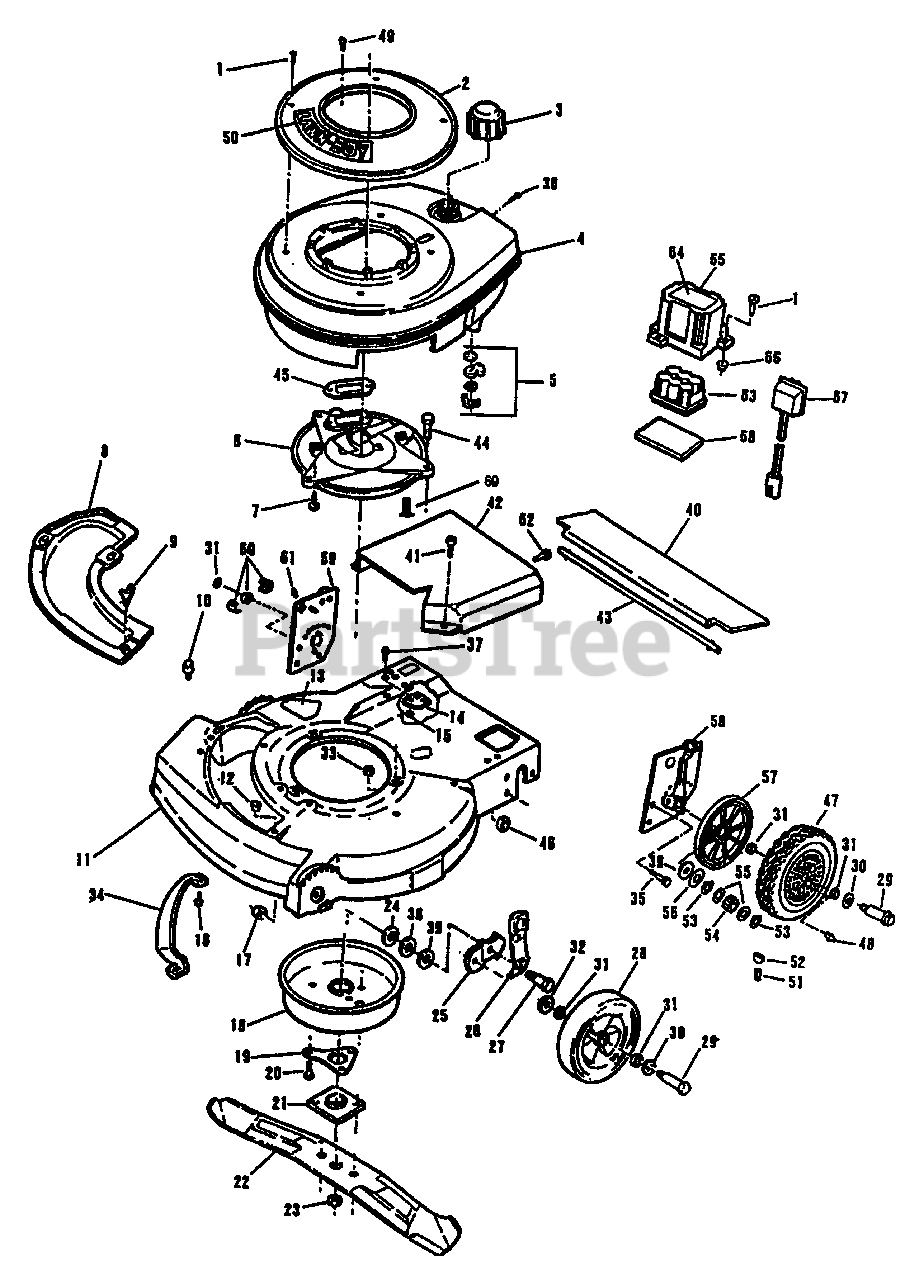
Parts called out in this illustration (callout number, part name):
1	Screw
2	Starter Base and Nut Assembly
3	Fuel Cap
4	Shroud-Engine
5	Fuel Shut-Off Assembly
6	Plate Muffler
7	Screw-Muffler Plate to Block
8	Cover Plate
9	Wing Screw
10	Screw-Plate and Chute Mounting
11	Housing Assembly
12	Grommet
13	Decal-Blade Contact Warning
14	Bolster-Housing
15	Nut-Bolster to Housing
16	Screw
17	Nut
18	Muffler Cover Assembly
19	Support-Crankshaft
20	Screw-Muffler to Muffler Plate
21	Collar and Plate Assembly
22	Blade-21"
23	Nut-Blade
24	Washer
25	Bracket-Wheel Height Adjust
26	Knob and Spring Assembly
27	Bolt-Shoulder
28	Wheel-Front
29	Bolt-Wheel
30	Washer-Felt
31	Washer-Felt
32	Washer
33	Nut-Muffler Plate to Housing
34	Toe Bar
35	Screw-Handle Bracket
36	Screw-Shroud to C.D. Bracket
37	Screw-Bolster to Housing
38	Washer-Shim-Wheel Height Adjust Bracket
39	Washer-Shim-Wheel Height Adjust Bracket
40	Shield-Trailing
41	Screw-Drive Cover Mounting
42	Cover-Drive
43	Rod-Trailing Shield
44	Screw-Muffler Plate to Housing
45	Gasket-Exhaust
46	Locknut-Hdl. Brkt. to Housing
47	Rear Wheel
48	Lube Fitting
49	Screw-Starter Mounting
50	Applique-Starter Base
51	Spring
52	Key
53	Retaining Ring
54	Pinion
55	Spacer
56	Washer
57	Cover-Rear Wheel
58	Height Adjuster Assembly-L.H.
59	Height Adjuster Assembly-R.H.
60	Bearing and Retainer Assembly
61	Fitting
62	Screw
63	Battery Pack Assembly
64	Decal-Battery
65	Cover-Battery
66	Grommet-Battery Mounting
67	Battery Charger Assembly
68	Pad-Battery
69	Screw-Muffler Plate To Block
